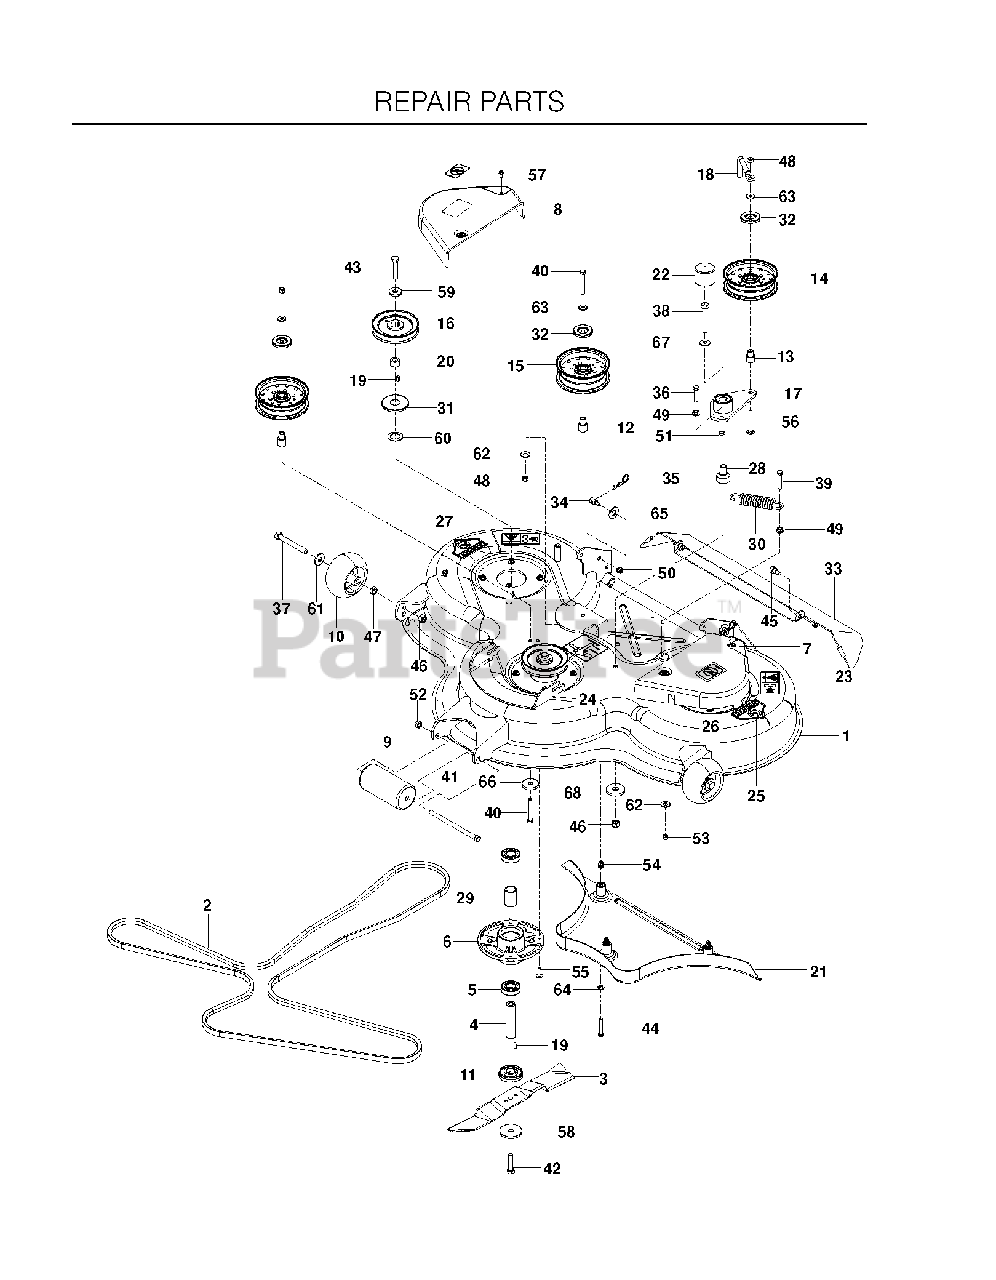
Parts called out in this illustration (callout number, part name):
3	BLADE
5	BALL BEARING
6	BEARING HOUSING
7	SHIELD.BELT.LT.48".COMBI-DECK
8	BELT.SHIELD.RT
9	ROLLER
10	GAUGE WHEEL
11	BUSHING, BLADE
12	IDLER BUSHING
13	BUSHING, IDLER
14	IDLER PULLEY
15	IDLER PULLEY (TALL)
16	PULLEY, 48
17	ARM-IDLER W/BRG
18	BELT KEEPER 5"
20	KEY RETAINER
21	PLUG, MULCH, ORANGE
22	CAP, VINYL
23	DECAL, BELT DRIVE
24	DECAL, BELT ROUTING
25	DECAL, CPSC
26	DECAL, NO STEP
27	DECAL, 122
28	PIVOT, BEARING
31	BOTTOM DUST CAP
32	DUST SHIELD
33	GUARD, DISCHARGE, BLK
34	STUD.FASTNER.W/ANTI-ROTATE
35	HAIRPIN #4
36	HCS 3/8-16 X 1-1/2
37	HCS 1/2-13 X 4 GR 5 ZD
38	SCREW, 1/2C X 3 HEX CAP
39	HCS 3/8C X 2
40	SCREW 3/8C X 2 3/4 HEX CAP
41	HCS 7/16-14 X 7 GR5 ZD
42	HCS M12 X 1.75 X 50 GR8.8 ZD
43	HCS M12 X 1.75 X 60 GR5 ZD
44	HCS M8 X 1.25 X 50 GR8.8 ZD
45	SB 3/8-16 X 3/8 SKT HD ZD
46	RP NUT 1/2-13 HEX NYLOC ZD
47	NUT 1/2 HEX JAM
48	NUT 3/8-16 NYLOC
49	NUT 3/8C WHIZ
50	5/16-18 NYLOC FLANGE NUT
51	NUT 3/8-16 HEX JAM
52	NUT 7/16C CENTERLOCK
53	NUT HEX 3/8-16 NYLON, THIN
55	RHSNB 5/16C X 1
56	RHSNB 3/8-16 X 2.75
57	SCREW 1/4 X 5/8
59	WASHER-.533IDX1.37OD
60	WASHER-1.06IDX1.63ODX.06
61	WASH USS FLAT 1/2
62	RP WASHER 3/8 FLAT
63	WASHER, 3/8 THICK
64	FLAT WASHER 5/16 SAE
65	WASHER 5/8 FLAT
66	SPINDLE WASHER
67	CONTACT BELLSPR 1/2
68	WASHER, SUPPORT
